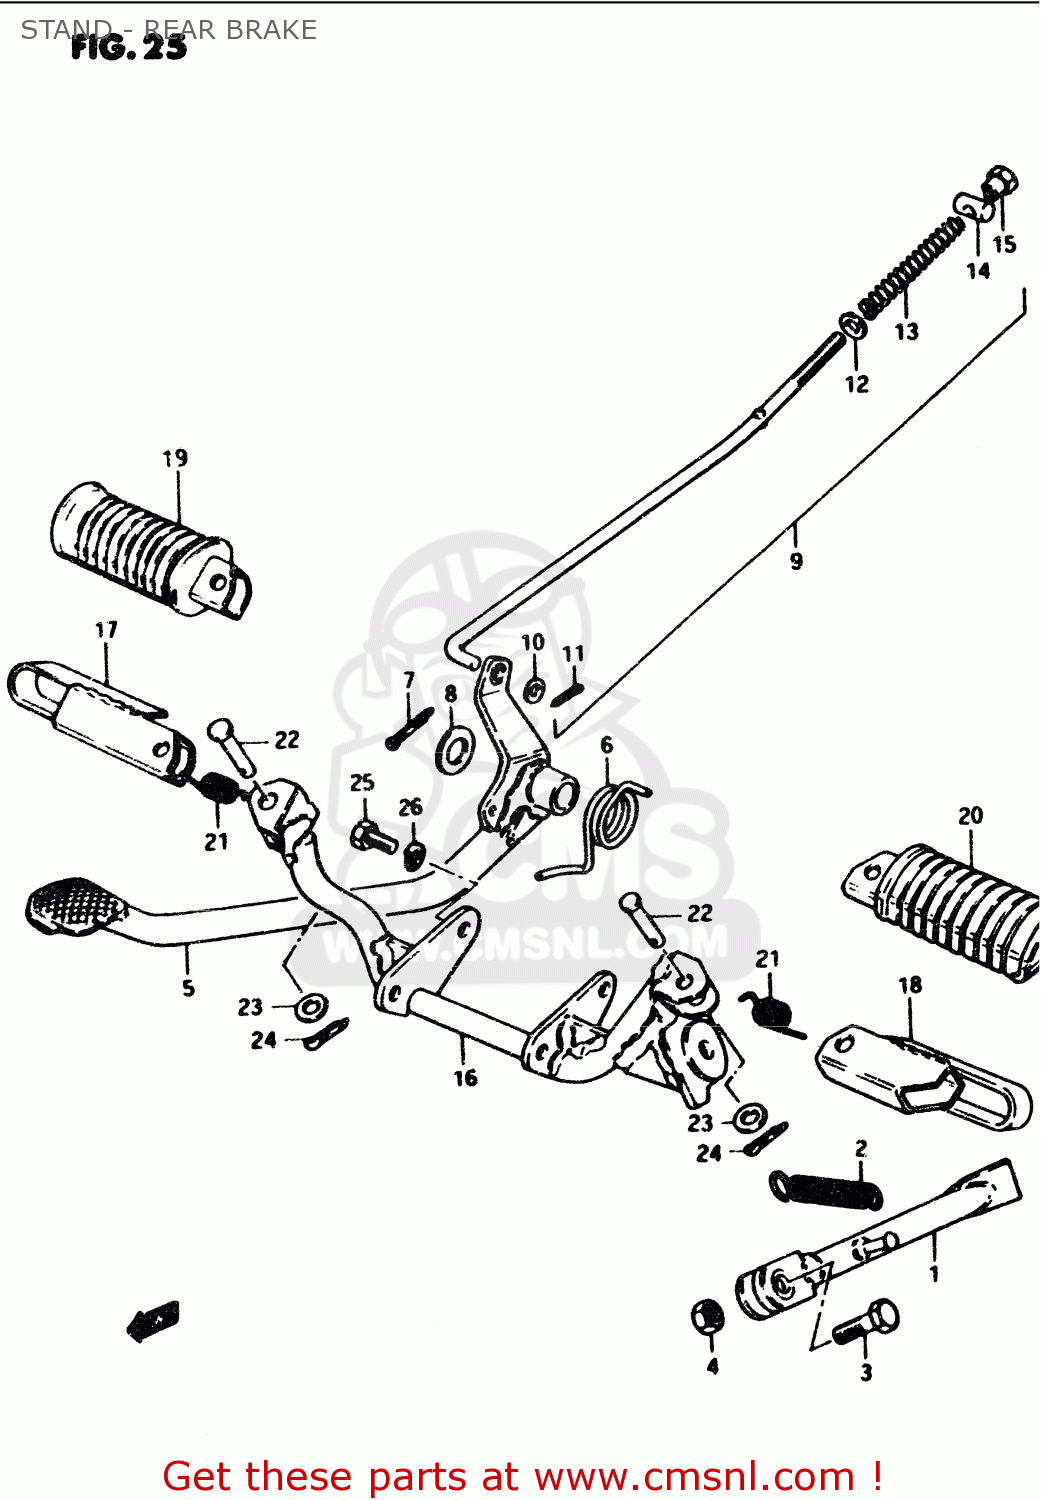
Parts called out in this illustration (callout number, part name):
1	STAND,PROP
2	SPRING
3	BOLT
4	NUT
5	PEDAL,BRAKE
6	SPRING
7	COTTER PIN
8	WASHER(15.5X26X2.3)
9	ROD ASSY,RR BRAKE
10	WASHER
11	PIN 20X20
12	WASHER
13	SPRING
14	PIN(11X18)
15	NUT (6MM)
16	BAR, FRONT FOOTREST
17	FOOTREST,FR,R
18	FOOTREST,FR,L
19	RUBBER,FRONT FOOTREST
20	FOOTREST
21	SPRING
22	PIN
23	WASHER
24	PIN 20X20
25	BOLT,8X16
26	LOCK WASHER
